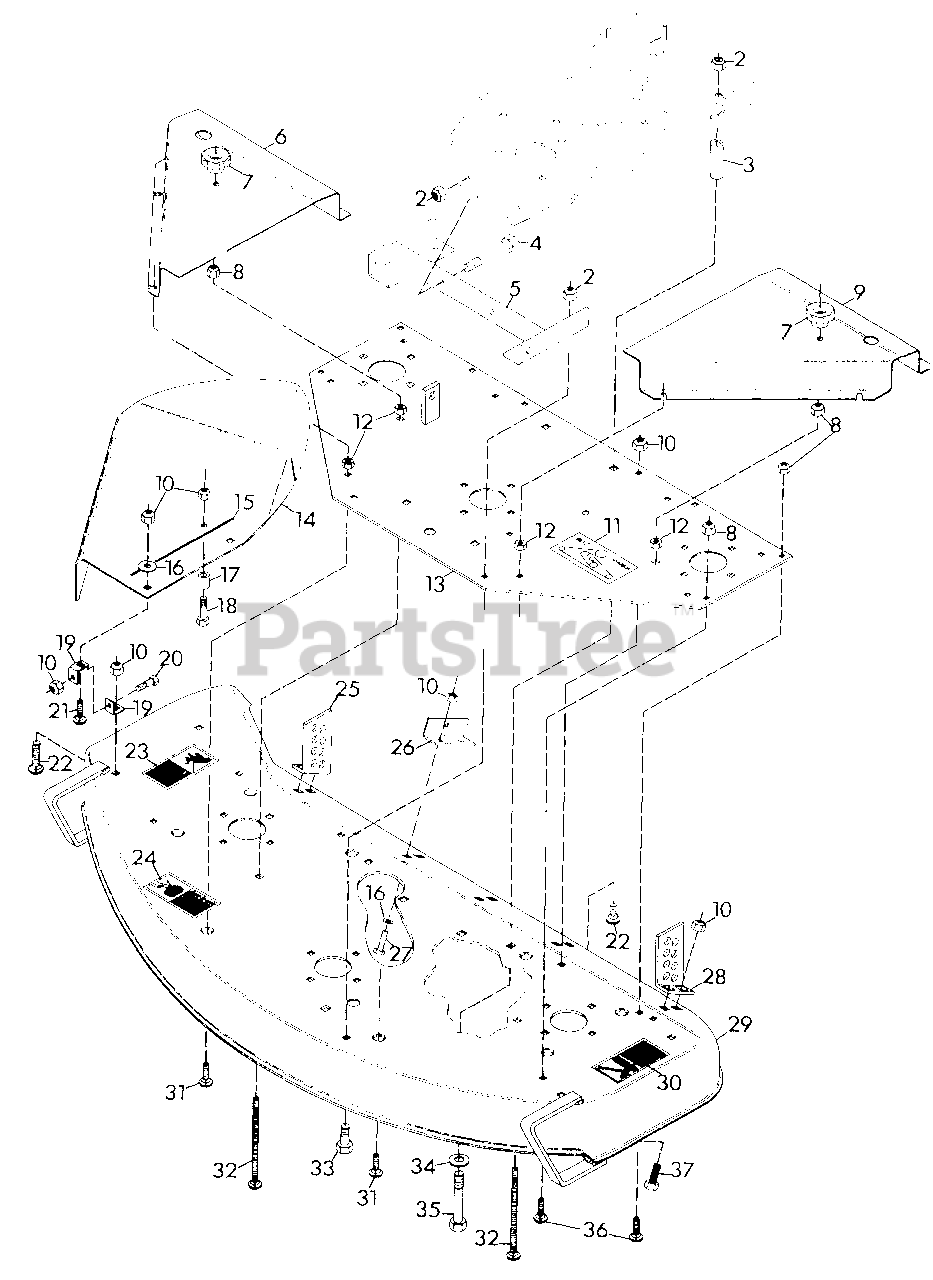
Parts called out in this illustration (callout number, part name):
1	SUPPORT, GEAR HOUSING
2	NUT, LOCK 1/2-13
3	SPACER, .510X.840X2.43
4	BOLT, HEX 1/2-13X1.375
5	BRACKET, HEIGHT ADJUSTMENT
6	COVER, PULLEY R.H.
7	KNOB
8	NUT, LOCK 5/16-18
9	COVER, PULLEY L.H.
10	NUT, LOCK 3/8-16
11	DECAL, BELT INSTALLATION
12	NUT, JAM 5/16-18
13	WELDMENT, SUPPORT PLATE
14	SHIELD, SAFETY EXTENSION 50" MOWER
15	STRIPE
16	WASHER, FLAT .406X.812X.065
17	STOP, CHUTE
18	BOLT, HEX 3/8-16X1.50
19	TAB, SPRING
20	BOLT, HEX 3/8-16X.875
21	BOLT, 3/8-16X1.00 RD HD SQ NK
22	BOLT, 3/8-16X.75 RD HD SQ NK
23	DECAL, DANGER HAND
24	DECAL, WARNING EYE
25	PLATE, BEAR ADJUSTMENT
26	BRACKET, LIFT
27	BOLT, HEX 3/8-16X1.00
28	PLATE, REAR ADJUSTMENT
29	WELDMENT, 50 INCH DECK
30	DECAL, DANGER FOOT
31	BOLT, CARRIAGE 5/16-18X1.00
32	BOLT, HEX 5/16-18X3.50
33	BOLT, HEX 1/2-13X1.25
34	WASHER, FLAT .531X1.062X.095
35	BOLT, HEX 1/2-13X3.75
36	BOLT, 5/16-18X.75 RD HD SQ NK
37	BOLT, HEX 3/8-16X1.25
